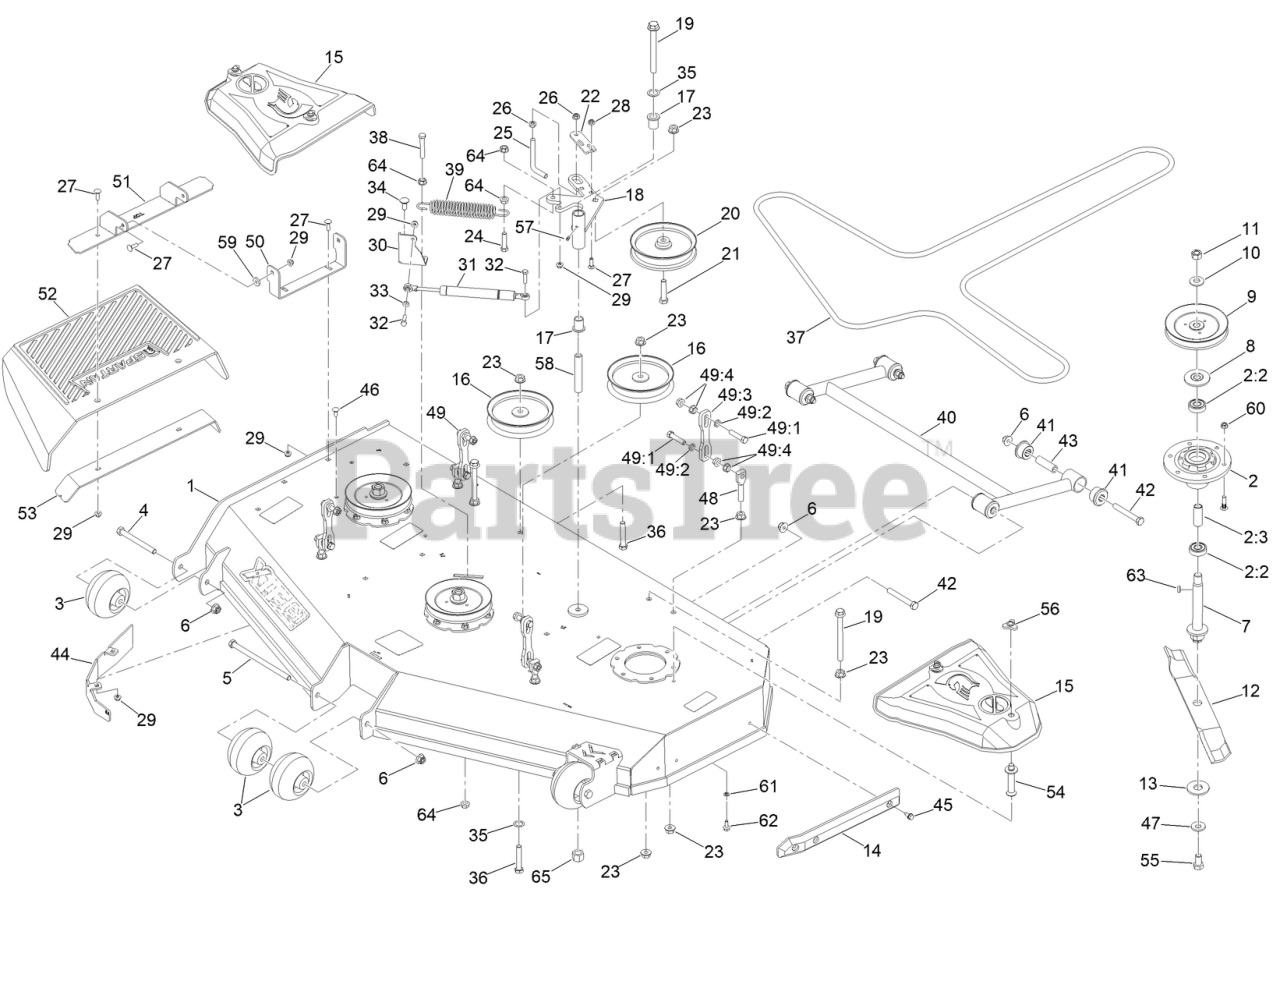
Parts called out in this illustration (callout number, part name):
1	ASM-DECK W/DECALS
2	SPINDLE ASM 6" DECK
2:2	BEARING-BALL
2:3	SPACER, BEARING
3	MWR ANTI-SCALP WHL W/O GREASE FITTING
4	SCREW-HH
5	1/2-13 X 8-1/2 HEX C/S GR 2 ZINC YELLOW
6	NUT-LOCK
7	SHAFT - SPINDLE
8	GUARD,BEARING TOP .989
9	PULLEY
10	M20 SPRING WASHER (44.5MMOD/ 3.3MM THK)
11	M20X1.5 C8.8 HEX NUT
12	BLADE-ROTARY
13	WASHER-HEX
14	MWR NYLON DECK GUARD
15	COVER-BELT
16	6-3/4IN IDLER PULLEY 15/16IN SPACER ASSY
17	3/4IN ID X15/16IN OD X 1-1/8IN FLNG BUSH
18	MWR DECK IDLER PULLEY ARM ASSY PAINT
19	1/2-13 X 5-1/2 HEX FLANGE BOLT GR 8 ZY
20	6-3/4IN IDLER PULLEY 7/16IN SPACER ASM
21	SCREW-HH
22	DECK IDLER PULLEY BELT RETNR BRKT PAINT
23	NUT-HHF
24	SCREW-HH
25	BOLT-L
26	3/8-16 HEX FLANGE NUT W/SERR ZINC YELLOW
27	5/16-18 X 1 CARRIAGE BOLT GR 8 YZ
29	NUT-HF, NI
30	DECK BELT IDLER DAMPER MTG BRKT PAINTED
31	IDLER GAS SPRING
32	SCREW-HH
33	.312IDX.625ODX.062 THK THRUST BRG OI BRZ
34	SCREW-CARR
35	.767IDX1.125ODX.016 THK TRIP WV WASHER
36	1/2-13 X 2-3/4 HEX FLANGE BOLT (GR.8) YZ
37	61 DECK BELT
39	MWR DECK SPRING
40	54IN/61IN DECK FRAME STABILIZER PAINTED
41	RED A80 SUSP BUSHING
42	1/2-13 X 3-3/4 HEX C/S (GR.5) ZC/YEL
43	UTV A-ARM BUSHING SLEEVE
44	BAFFLE-WIPER
45	SCREW-HWH, THREAD CUT
46	BOLT-CARR
47	M16 SPRING WASHER (39MMOD/ 3.9MM THK)
48	MWR DECK HEIGHT ADJUSTMENT STUD
49	MWR DECK SUSP LINK ASSY
49:1	MWR DECK SUSP LINK PAINT
49:2	SCREW-HH
49:3	.443 ID X .749 OD X .125 THK NYLON BLACK
49:4	NUT-HF
50	MWR CHUTE MTG BRKT PAINTED
51	RT/SRT DECK CHUTE HINGE ASSY PAINT
52	2020 RT/SRT RUBBER DISCHARGE CHUTE
53	2020 DECK CHUTE HINGE BACKER BRKT PAINT
54	PIN-BELT COVER
55	M16X1.5-30MM C10.9 HEX BOLT
56	NUT-KNOB
57	1/4IN DRIVE TYPE GREASE FITTING YZ
58	MWR INNER IDLER SPACER
59	.312 ID X .875OD X .1875 THK F/W NYL
61	WASHER-LOCK
62	SCREW-HHF
63	6MM X 6MM X 20MM ROUNDED MACHINE KEY
64	NUT-HF
65	NUT-LOCK, NI
